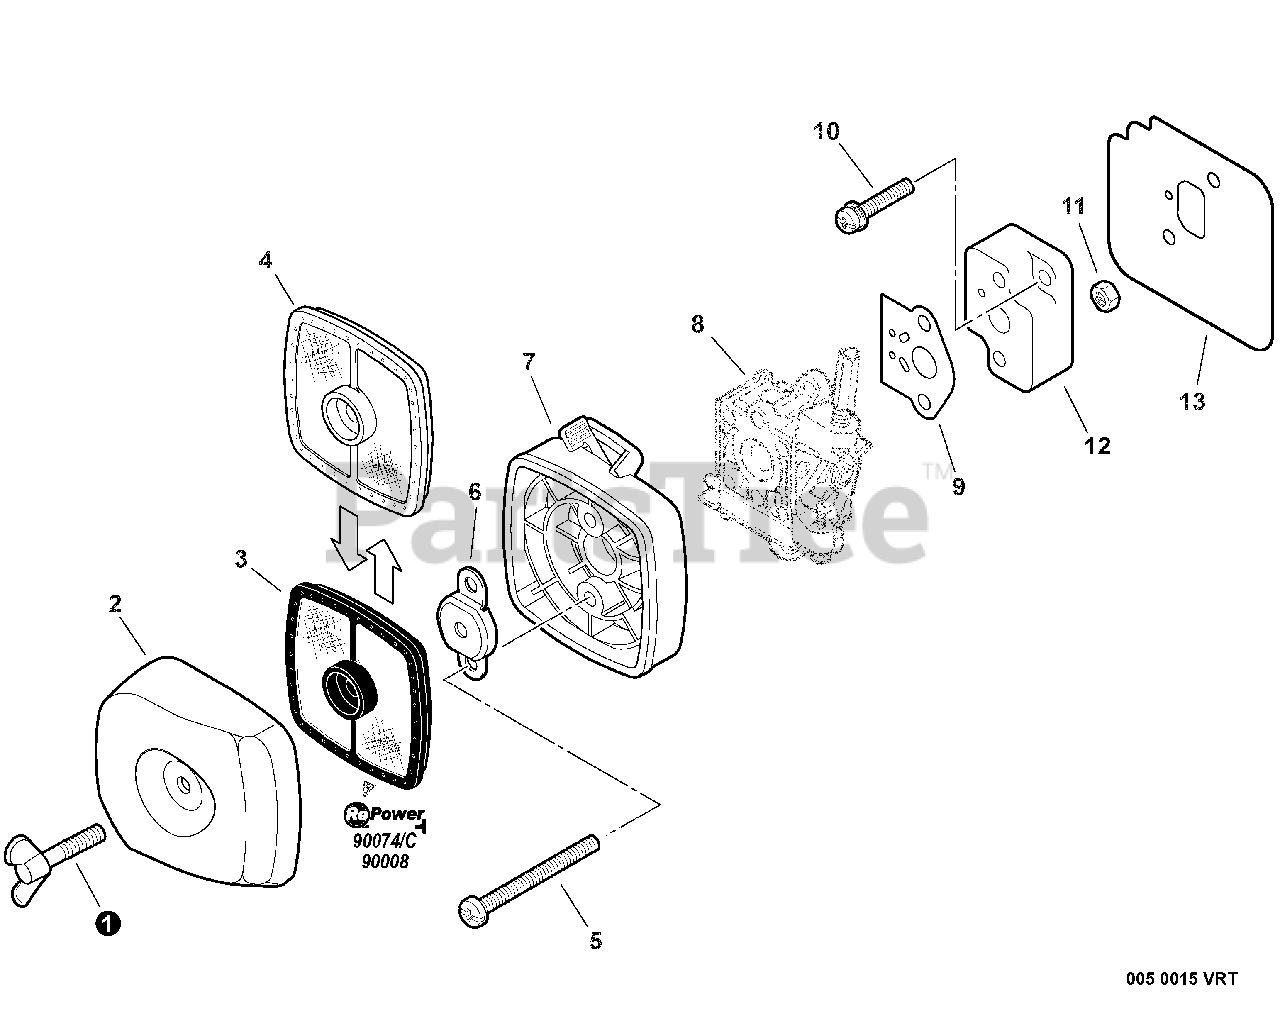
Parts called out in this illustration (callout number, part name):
1	BOLT, WING 5×20
2	COVER, AIR FILTER - GRAY
2	COVER, AIR FILTER - BLACK
3	FILTER, AIR - DOUBLE LAYER
4	FILTER, AIR - SINGLE LAYER
5	SCREW 5×65
6	PLATE, PREVENT
7	CASE, AIR FILTER - GRAY
7	CASE, AIR FILTER - BLACK
8	CARBURETOR
9	GASKET, CARBURETOR
10	SCREW 5×22
11	NUT M5
12	INSULATOR, INTAKE
13	HEAT SHIELD, INTAKE
14	TUNE-UP KIT - REPOWER
15	FILTER KIT - REPOWER
